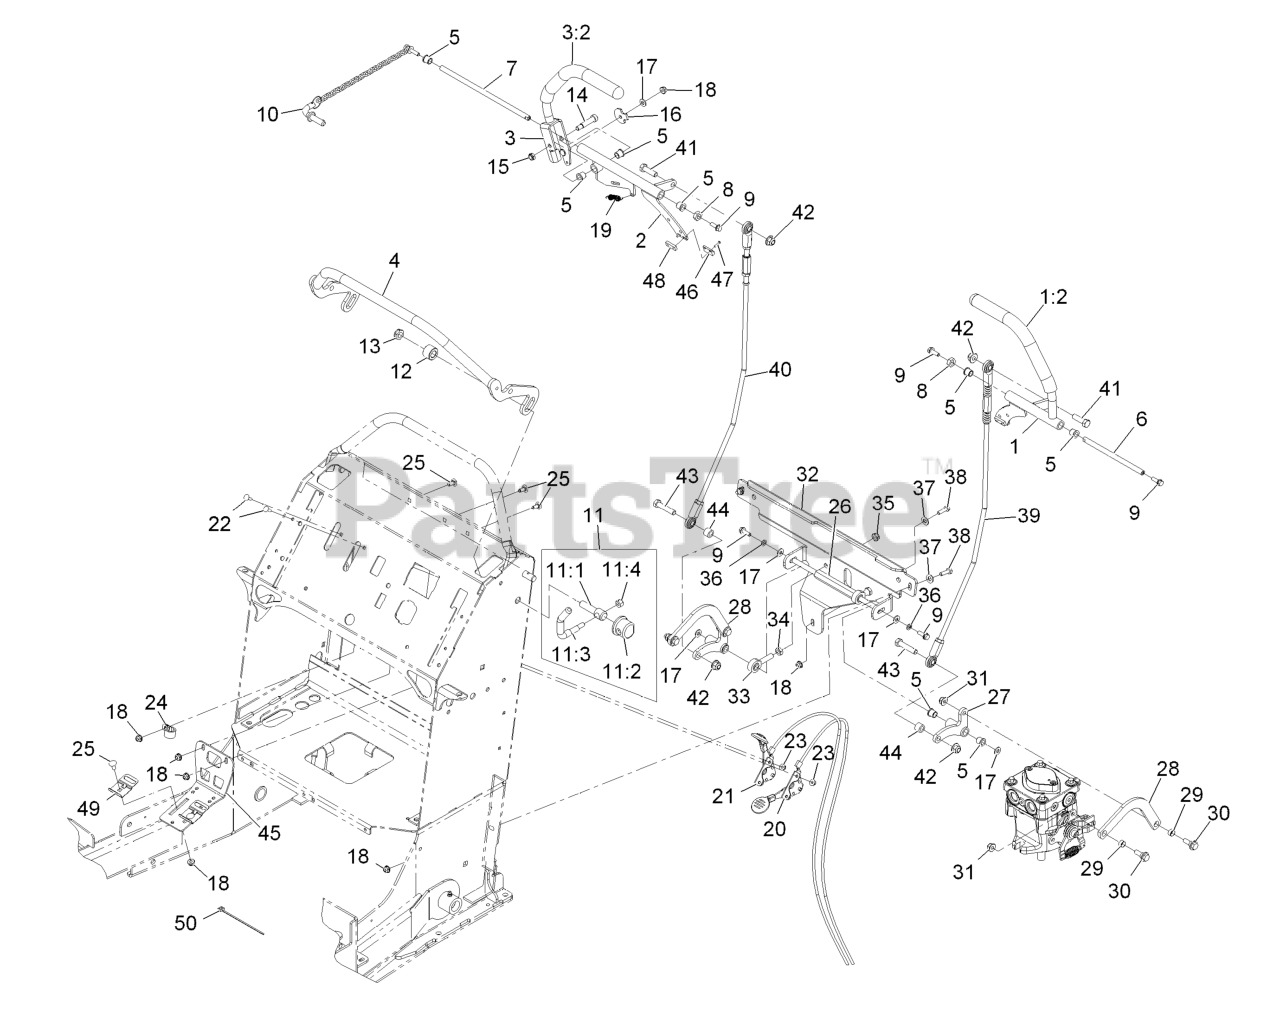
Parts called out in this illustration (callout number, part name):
1	LEVER ASM, LH
1:2	GRIP-HANDLE, CONTROL
2	MOTION CONTROL ASM-RH
3	LEVER ASM, RH
3:2	GRIP-HANDLE, CONTROL
5	BEARING
6	SHAFT-PIVOT, MOTION CONTROL
7	SHAFT-PIVOT, MOTION CONTROL
8	SPACER-SHAFT, DRIVE LEVER
9	SCREW-HHF
10	HOC PIN ASM
11	LEVER ASM
11:1	SCREW-LOCK
11:2	CAP-LOCK
11:4	NUT-LOCK, NI
12	SPACER-CLAMP
13	NUT-HEX
14	SCREW-HSH
15	NUT-LOCK, NI
16	CAM-LEVER
17	WASHER-FLAT
19	SPRING-EXTENSION
20	CONTROL-THROTTLE
21	CONTROL-CHOKE
22	BOLT-CARR
23	NUT-LOCK, FLANGE
24	CLAMP-CABLE
25	SCREW-CARR
26	SHAFT-BELLCRANK PIVOT
27	BELLCRANK-CONTROL, MOTION
28	LINK-BELLCRANK, PUMP
29	BUSHING-SLEEVE
30	SCREW-SHOULDER
31	NUT-HF, NI
32	BRACKET-BELLCRANK
33	BALLJOINT
34	NUT-HJ
35	NUT-HEX
36	SCREW-HH
37	WASHER-PLAIN
38	SCREW-HH
39	LINKAGE-TRACKING CONTROL,LH
40	LINKAGE-TRACKING CONTROL,RH
41	SCREW-HH
42	NUT-HF, NI
43	SCREW-HH
44	SPACER-WHEEL
45	BRACKET, REED SWITCH
46	ACTUATOR-SWITCH, REED
47	SCREW-HH
48	PLATE-TAPPED
49	CLAMP, REED SWITCH
50	TIE-CABLE
